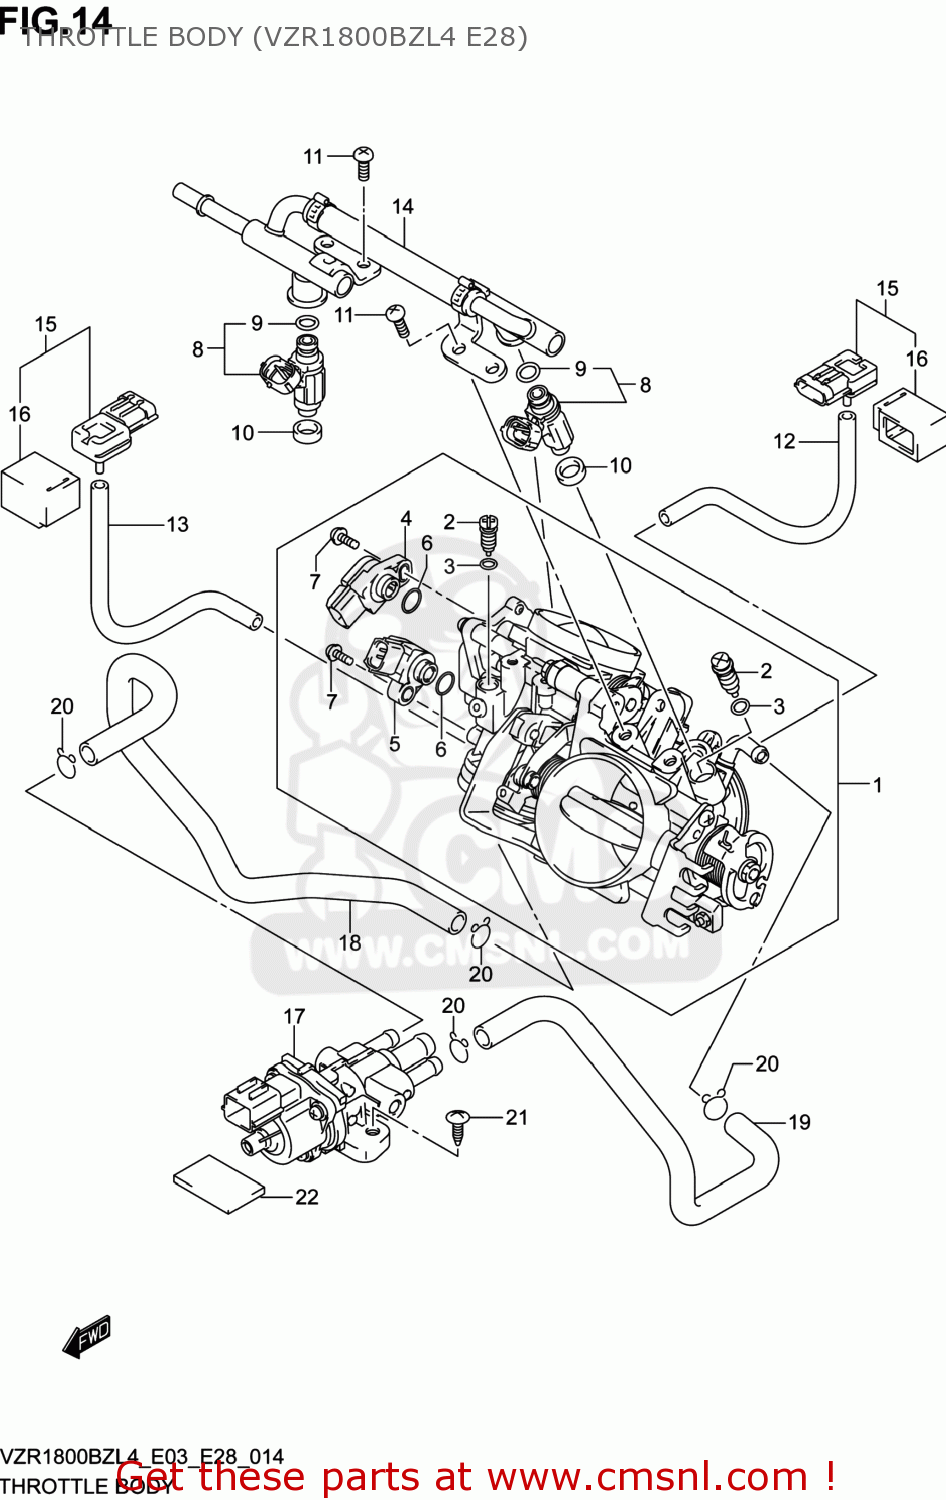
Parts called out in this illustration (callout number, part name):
1	BODY ASSY,THROTTLE
2	ADJUSTER
3	O RING
4	SENSOR ASSY
5	SENSOR ASSY
6	O RING
7	SCREW
8	INJECTOR ASSY
9	O-RING
10	SEAL
11	SCREW
12	HOSE
13	HOSE
14	PIPE ASSY,DELIVERY
15	SENSOR,AIR PRESSURE
16	COVER
17	VALVE,ISC
18	HOSE,ISC VALVE,R
19	HOSE,ISC VALVE,L
20	CLIP
21	SCREW
22	CUSHION,FUEL TANK NO.2
